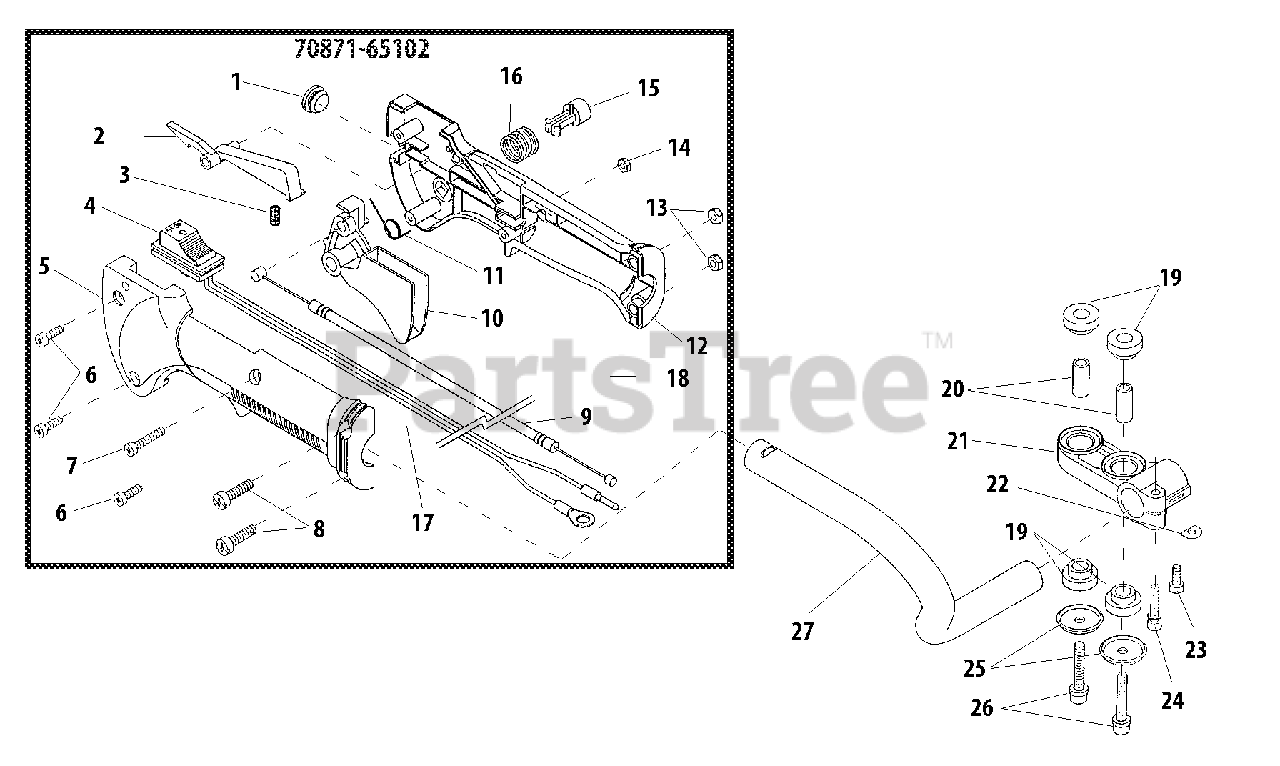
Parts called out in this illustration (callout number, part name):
1	PLUG, RUBBER
2	LOCKOUT, THROTTLE
3	SPRING, COMPRESSION
4	SWITCH ASSY, ON-OFF
5	BODY - LEFT
6	SCREW - 4×16 -- TAPPING
7	SCREW M4×23
8	SCREW M5×20
9	CABLE, THROTTLE
10	TRIGGER, THROTTLE
11	SPRING, TORSION
12	GRIP BODY - RIGHT
13	NUT M5
14	NUT M4
15	BUTTON, THROTTLE LOCK
16	SPRING, COMPRESSION
17	STRAP, TIE
18	TUBE, PROTECTIVE - CORRUGATED
19	CUSHION
20	COLLAR 6
21	HANDLE STAY
22	D-WASHER
23	BOLT 5×12
24	BOLT M5×25
25	WASHER 6
26	BOLT M6×35
27	HANDLE, REAR
70871-65102	THROTTLE LEVER ASSY
